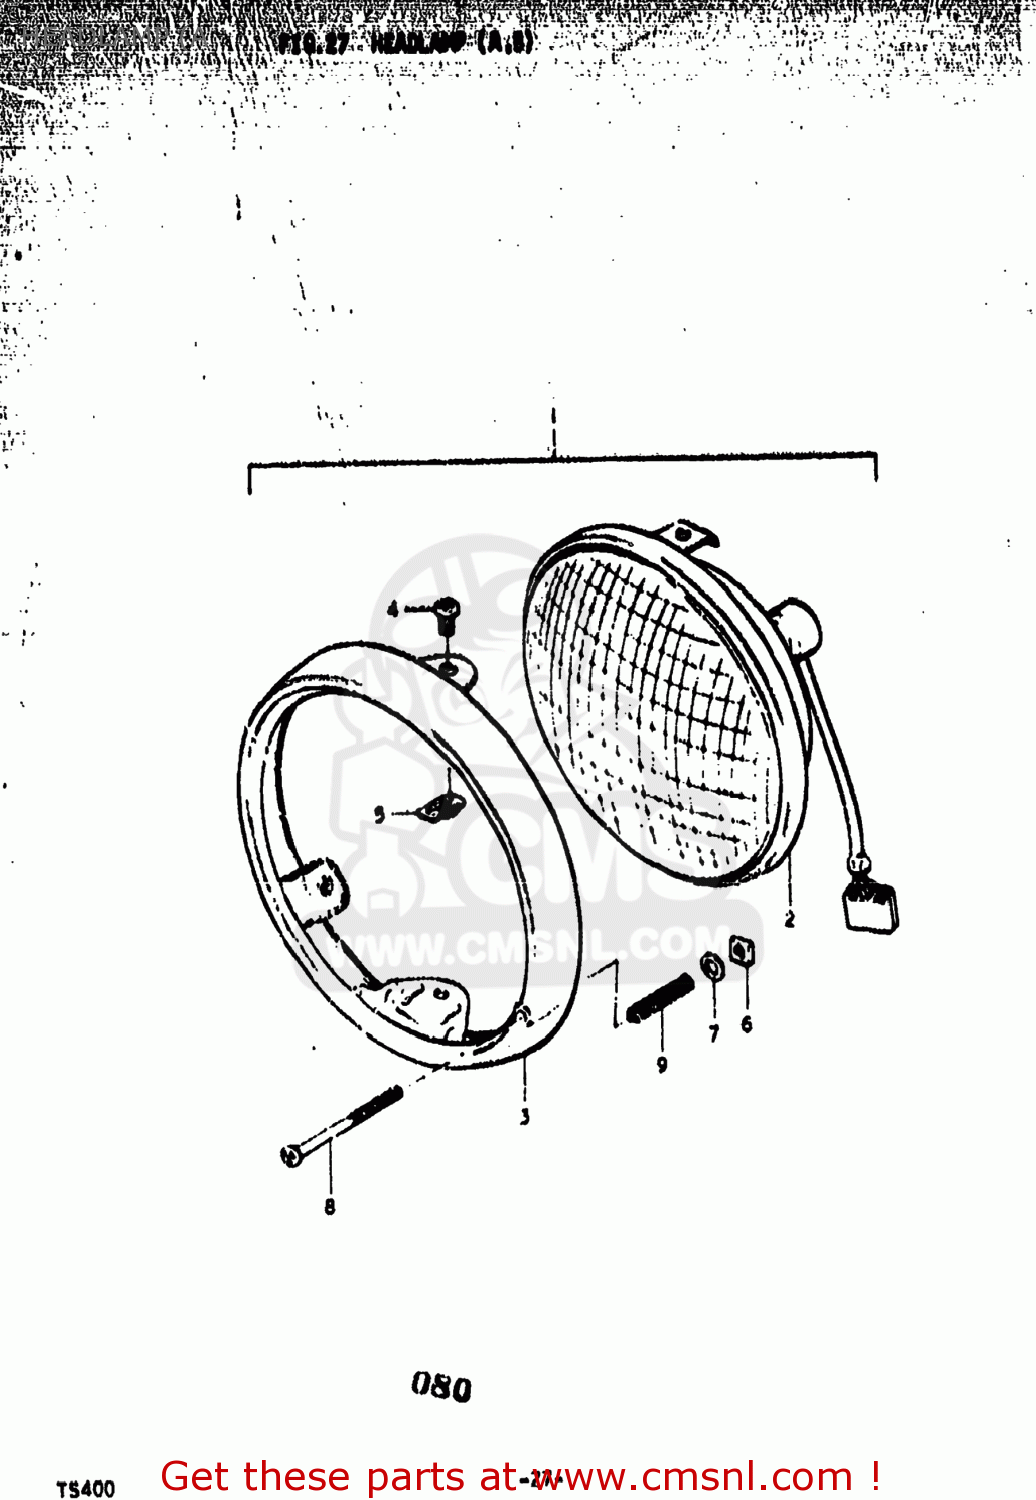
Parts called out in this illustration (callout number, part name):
1	HEADLAMP ASSEMBLY
2	LAMP UNIT
3	RIM,HEADLAMP
4	SCREW
5	NUT,ADJUSTING
6	NUT,HEADLAMP ADJUSTER
7	WASHER
8	SCREW,HEADLAMP ADJUST
9	SPRING,HEADLAMP ADJUST
